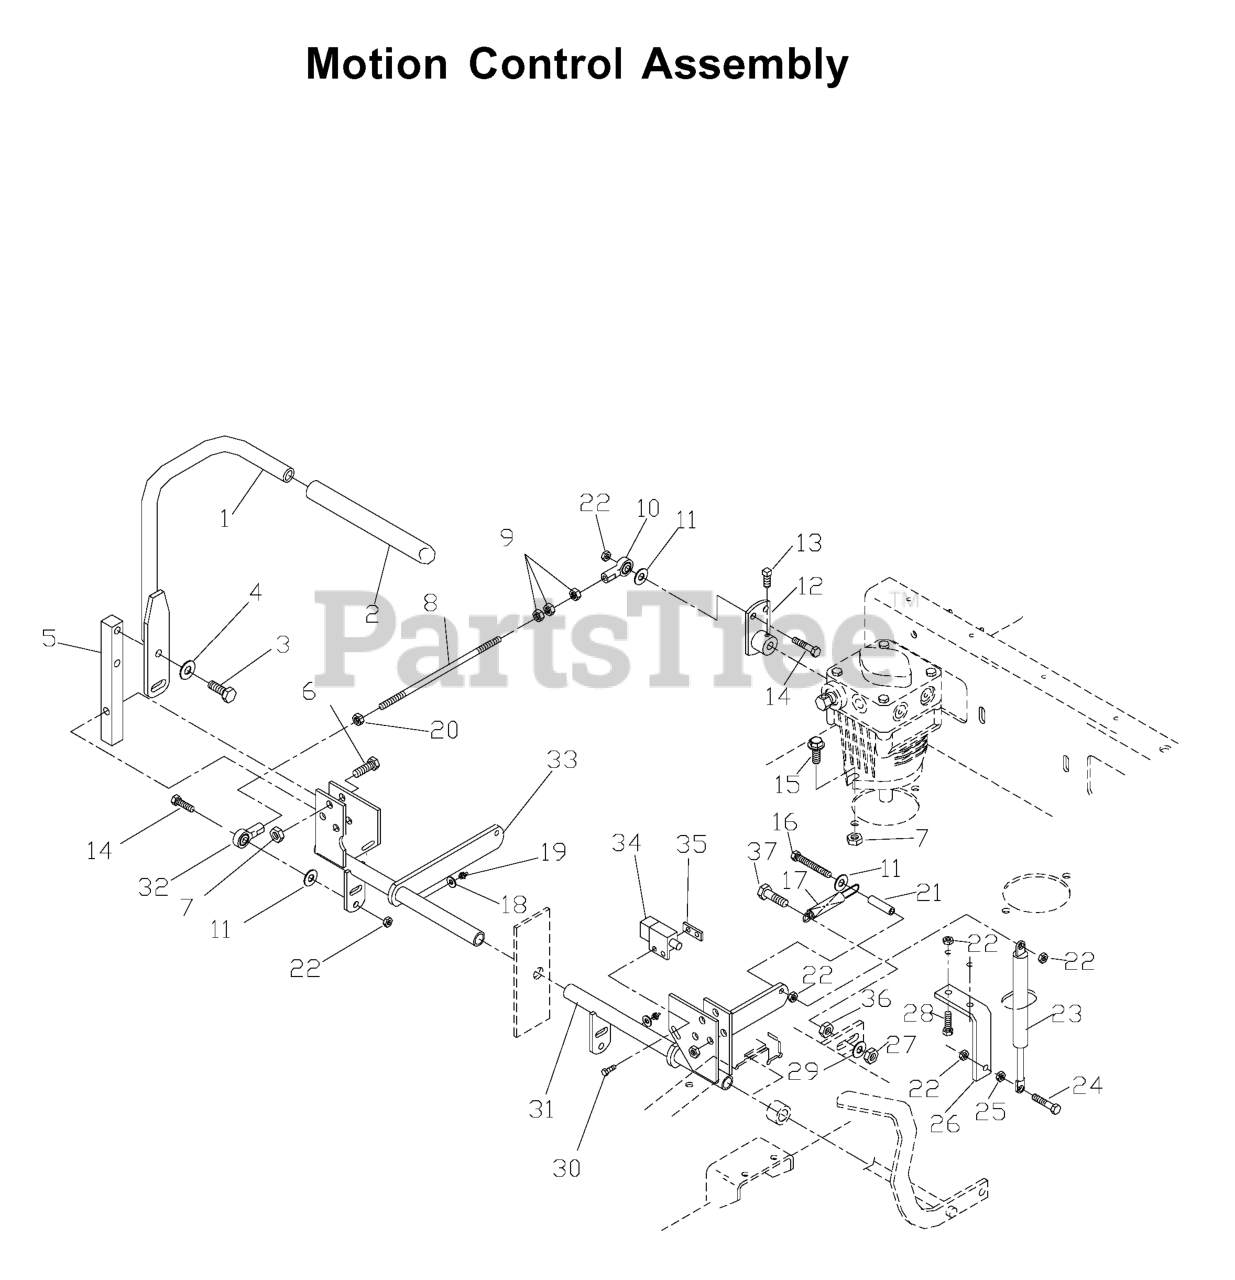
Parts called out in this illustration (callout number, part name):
1	CONTROL LEVER WELDMENT
3	HCS 3/8-16X1.GRD.5.ZD
4	WASHER, 3/8 DISC SPRING SPEC
5	CONTROL ARM
6	HCS 3/8C X 1 1/2
7	NUT 3/8C CENTERBLOCK
8	PUMP CONTROL LINK
10	BALL JOINT, RIGHT HANDED
11	WASHER 5/16 FLAT
12	PUMP LEVER
13	5/16C X 5/8 "V" POINT
14	HCS 5/16C X 1
15	4CS 3/8C X 1 SERRATED HEAD
16	TAP BOLT 5/16C X 2 1/4
19	ZERK
20	NUT 5/16F LEFTHAND
22	NUT 5/16C CENTERLOCK
24	HCS 5/16C X 1 1/4
25	NUT 5/16C WHIZ
26	BRACKET "I"
27	NUT 3/8-16 NYLOC
28	HCS 5/16C X 3/4
29	WASHER 3/8 FLAT
30	SCREW #10-24 X 5/8
31	CONTROL WELDMENT LT
32	BALL JOINT, LEFT HANDED
33	CONTROL WELDMENT RT.
34	SWITCH, INTERLOCK
35	TAPPED PLATE
36	NUT 3/8C WHIZ
37	HCS 3/8C X 2
